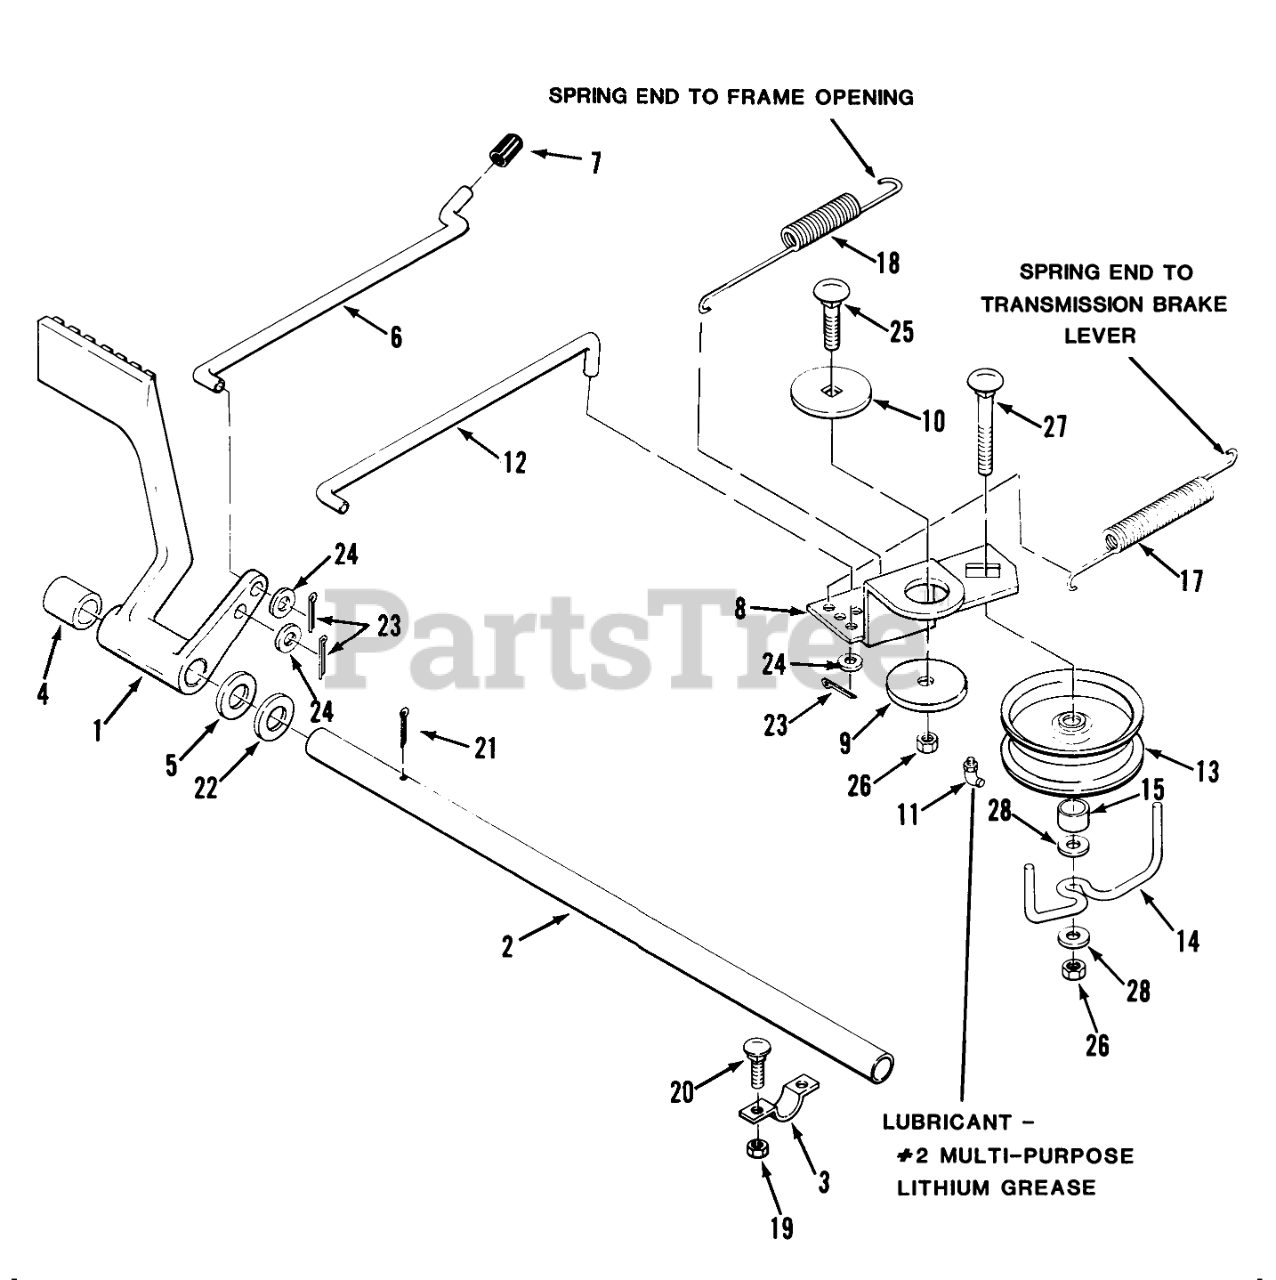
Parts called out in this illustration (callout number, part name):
1	PEDAL BRAKE R
2	SHAFT PEDAL
3	CLAMP
4	SPACER
5	WASHER-WAVE
6	Lock Rod
8	ARM-IDLER R
9	BUSHING
10	WASHER-BEARING
11	Fitting-Grease
12	ROD-CLUTCH/BRAKE B
13	PULLEY IDLER
14	GUIDE-BELT
15	SPACER
17	SPRING - BRAKE
18	SPRING - CLUTCH
19	Nut
20	Bolt
22	Washer
23	Cotter Pin
24	WASHER 5/16 SAE
25	Bolt
26	NUT
27	Carriage Bolt 3/8-16 x 2-1/4
28	Washer
